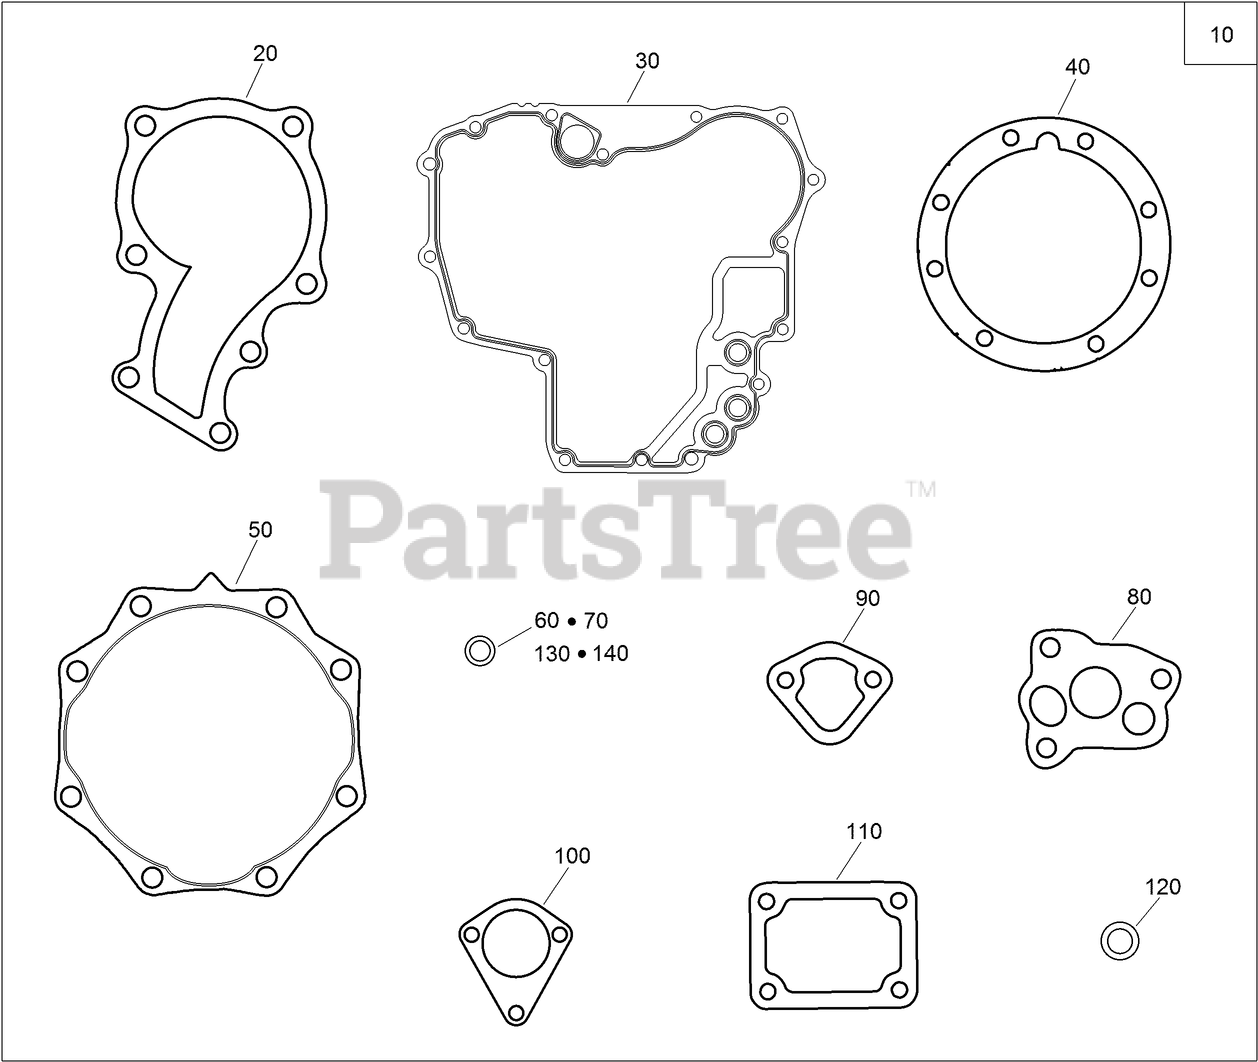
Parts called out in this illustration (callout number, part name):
10	LOWER GASKET KIT
20	GASKET-PUMP, WATER
30	GASKET-CASE, GEAR
40	GASKET-CASE, BEARING
50	GASKET-COVER, CASE
60	O-RING
70	O-RING
80	GASKET-PUMP, OIL
90	GASKET-PUMP, FUEL
100	GASKET
110	GASKET-PLATE, CONTROL
120	GASKET
130	O-RING
140	O-RING
